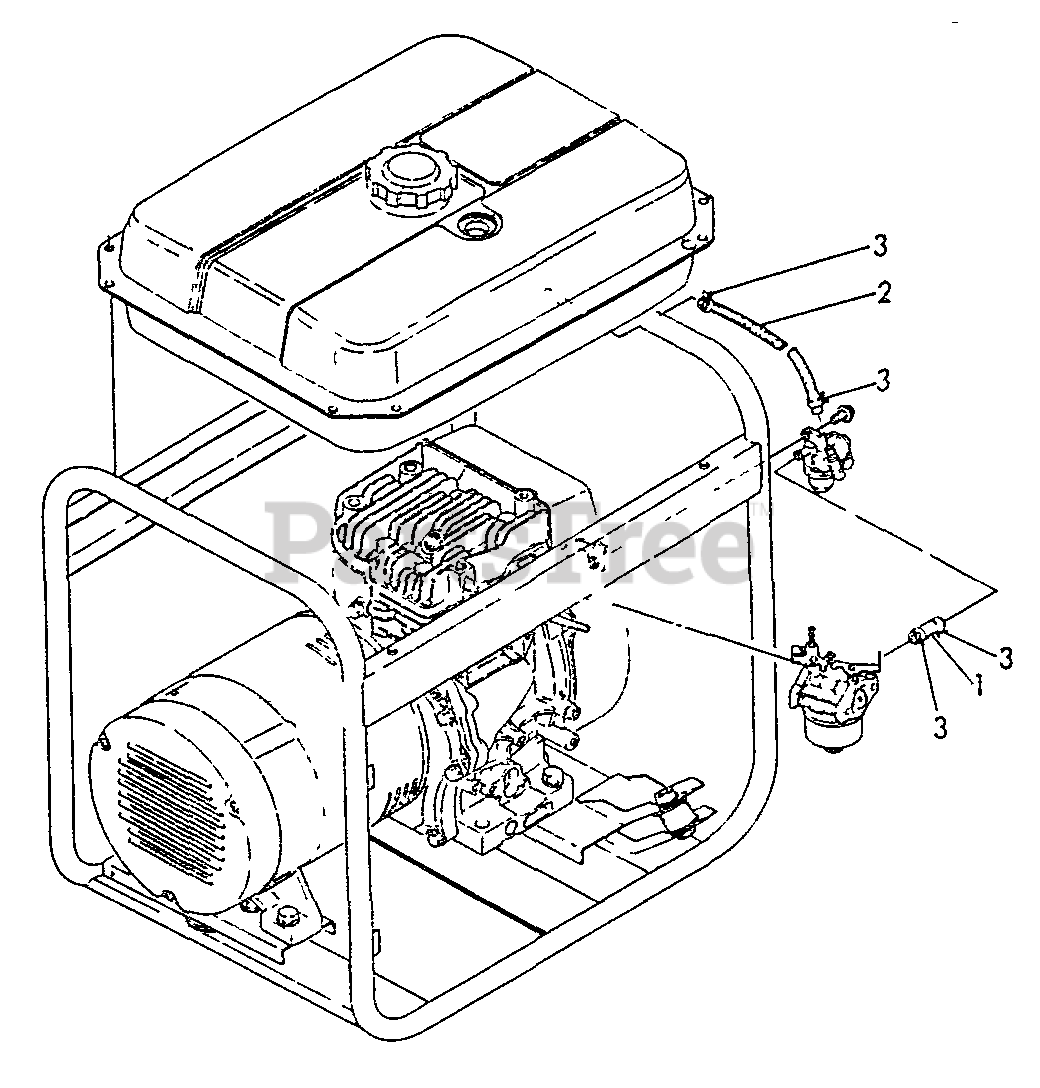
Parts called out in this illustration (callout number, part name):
1	PIPE, FUEL
2	PIPE, FUEL
3	CLAMP
